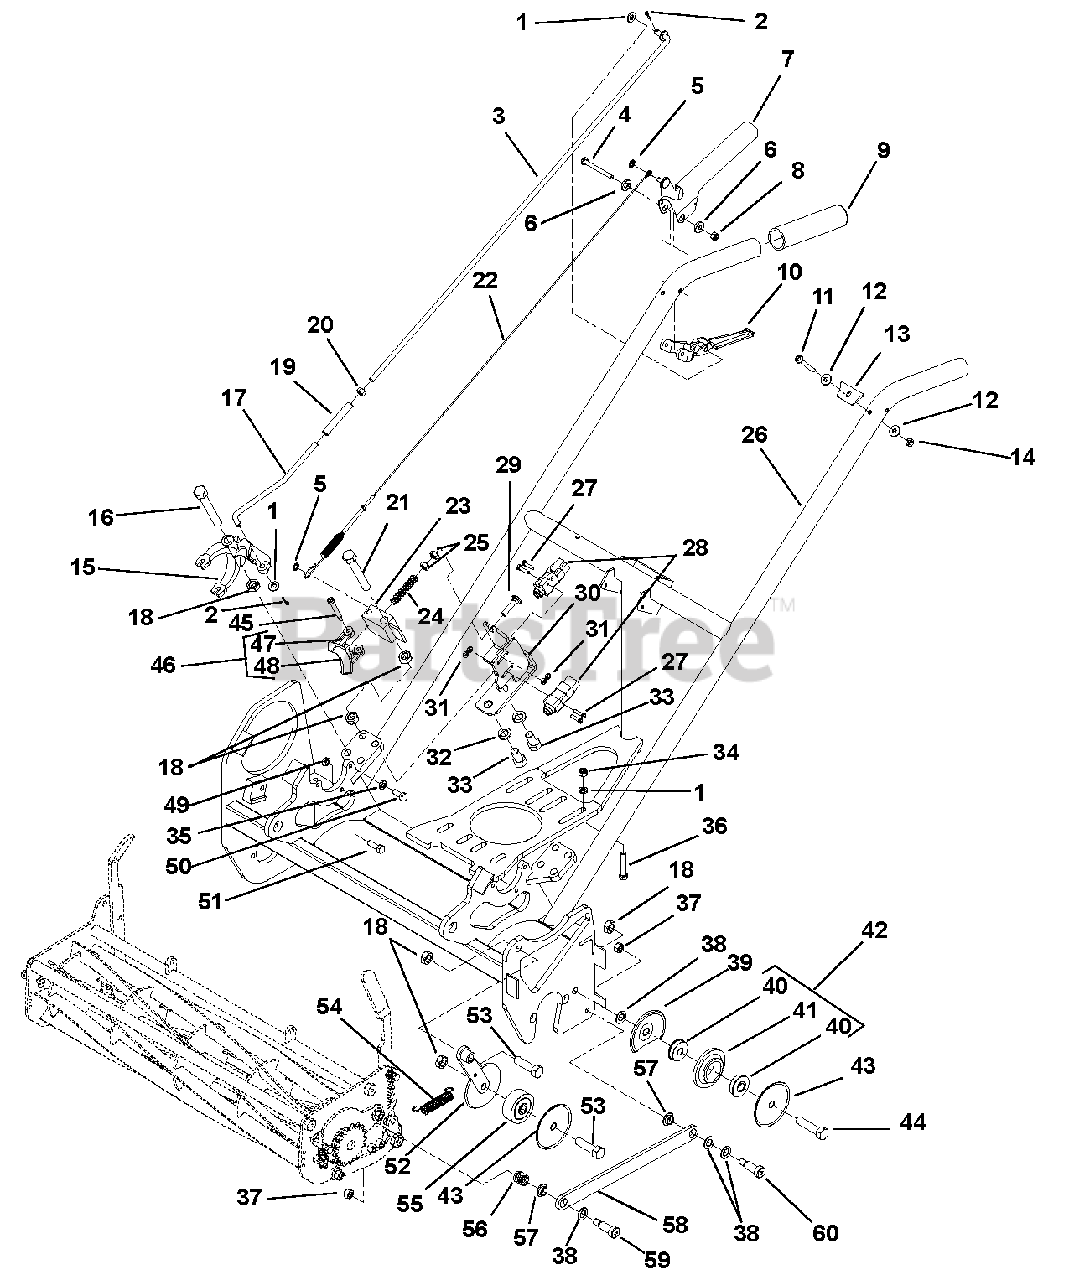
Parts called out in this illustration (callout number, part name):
1	Washer .312
2	Pin, Cotter
3	Rod, Clutch Straight
4	Cap Screw, Hex Head .25-20 2.75
5	Ring, Retaining .25
6	Bushing, Flange
7	Paddle, Clutch Hand
8	Nut, Hex .25-20 Nyloc
9	Grip
10	Lever, Clutch Hand
11	Screw, Pan Head Slotted .25-20 x 2
12	Washer, Flat .25
13	Stop, Handle
14	Nut, hex .25-20
15	Lever, Clutch Fork
16	Cap Screw, Hex Head .50-20 x 3.5
17	Angle Rod, Left
18	Nut, Jam .50-20
19	Rod, Clutch Coupler
20	Nut, Hex .312-24
21	Cap Screw, Hex Head .50-20 x 3
22	Cable Assembly, CL Brake
23	Block, Braking Right Hand
25	Nut, Hex .312-18
26	Frame Weldment, CL-125 (995310)
27	Screw, Pan Head Phillips 10-24 x .75
28	Switch, Double Pole Plunger
29	Bolt, Carriage .312-18 x 1.5
30	Weldment, Braking Retainer Right Hand
31	Nut, Nylock #10-24
32	Washer, Lock .50
33	Cap Screw, Hex Head .50-20 x 1
34	Nut, Hex .312-18 Nyloc
35	Washer, Lock .312
36	Bolt, Carriage .312-18 x 1.75
37	Nut, Hex .375-16
38	Washer, Metal Bushing .50 x 18 Gauge
39	Guard, Inner Chain (Cupped)
40	Bearing, Flange 1.375 O.D., .500 Bore
41	Shell, Chain Idler
42	Idler Assembly, Chain (Includes Items 40 and 41)
43	Disc, Chain Guide
44	Cap Screw, Hex Head .50-20 x 2
45	Pin
46	Brake Assembly (Includes Items 47 and 48)
47	Shoe, Brake
48	Pad, Brake
49	Nut, Jam .312-18
50	Cap Screw, Hex Head .312-18 x .75
51	Cap Screw, Hex Head .312-18 x 1
52	Bracket, Idler With Disc
53	Bolt, Idler .50-20 x 1.75
54	Spring, Idler High Tension
55	Idler
56	Spring, Reel
57	Bushing, Sintered Steel, Oil Impregnated
58	Arm, Reel
59	Screw, Shoulder .50 Diameter .38-16 x .75 Stainless Steel
60	Screw, Shoulder .50 Diameter .38-16 x 1 Stainless Steel
61	Sprocket, 10-Tooth
62	Spacer, Sprocket
63	Washer
64	Cap Screw, Hex Head 8 mm-1.25 x 20 8.8
